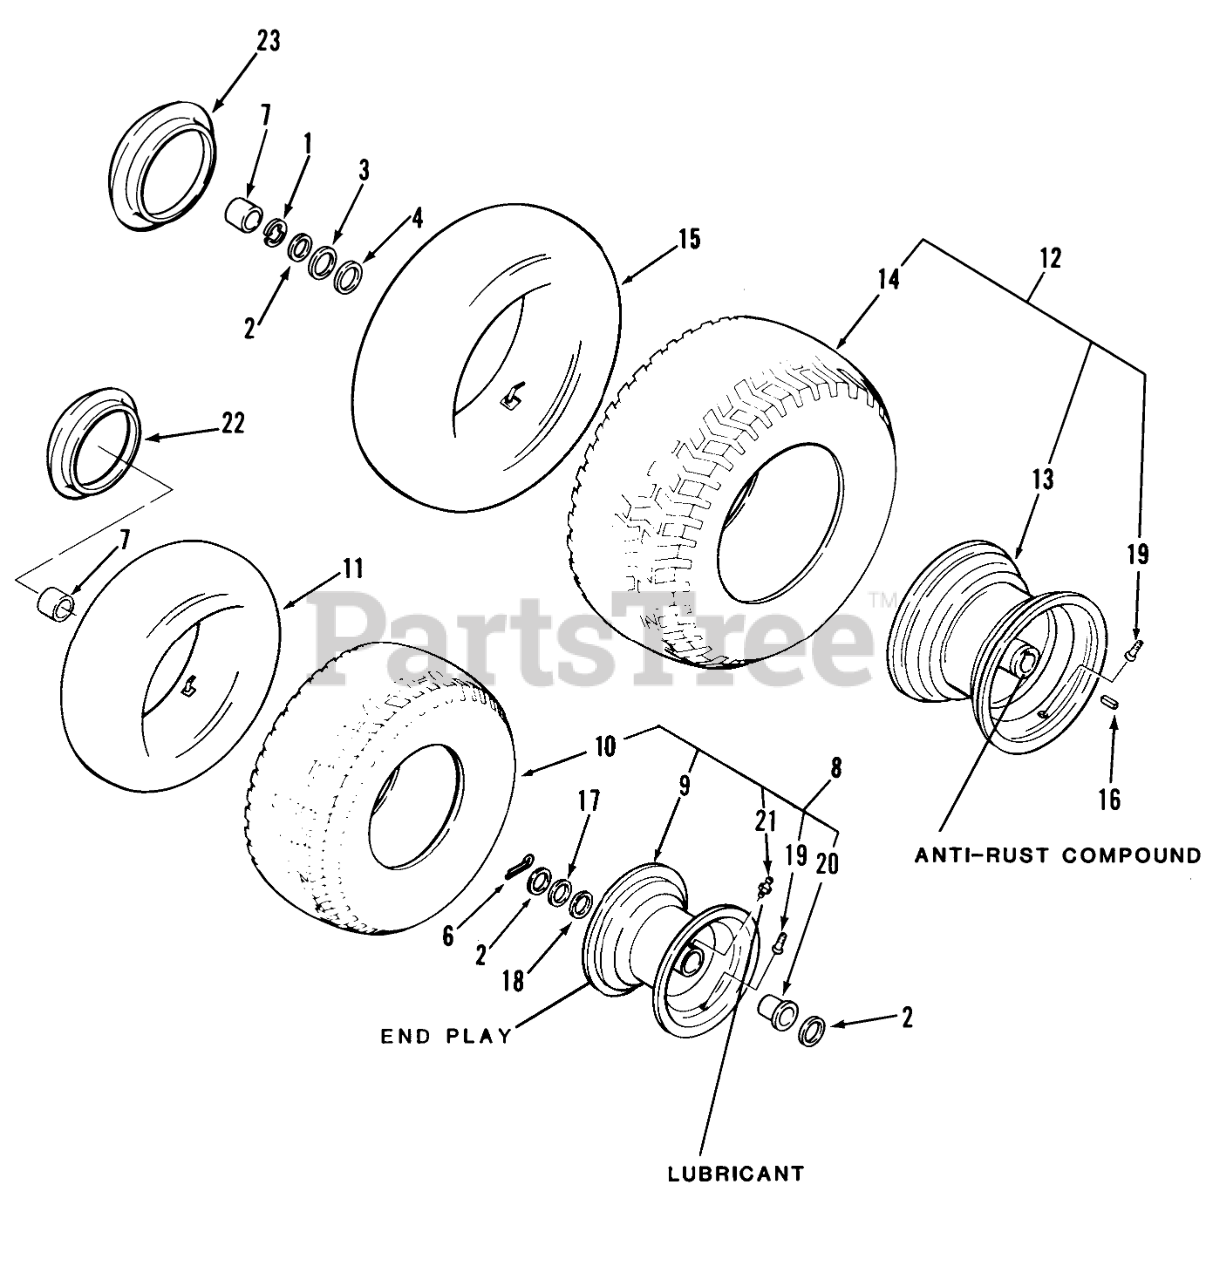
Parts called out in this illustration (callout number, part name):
1	E Ring
2	WASHER-FLAT
3	WASHER-SHIM
4	WASHER
6	COTTER PIN-4
7	HUB CAP
8	Assy-Wheel & Tire Front 208-3 Only
9	ASSY WHEEL
10	Tire-Front 13 X 5.00-6
11	Front Tube-Service Only
12	Assy-Wheel & Tire-Rear 208-3 Only
13	ASSY WHEEL
14	TIRE
15	Rear Tube-Service Only
16	SQ KEY
17	WASHER
18	WASHER-SHIM
19	VALVE
20	FLANGE BEARING
21	Zerk
22	HUB CAP 6 IN.
23	HUB CAP 10 IN.
